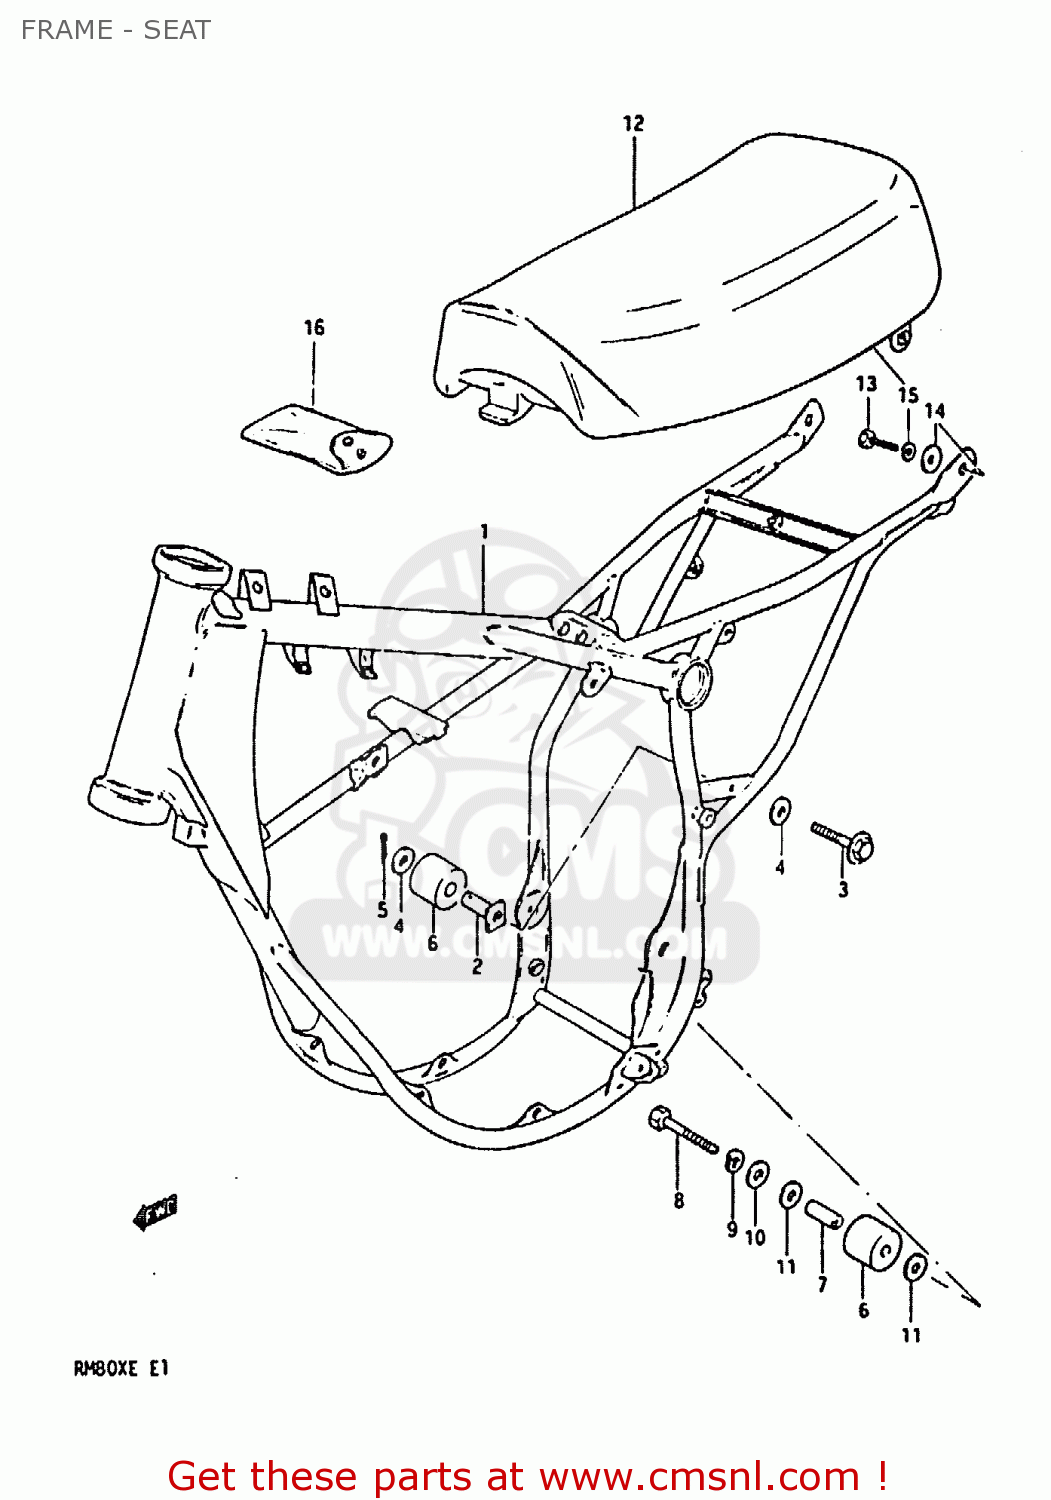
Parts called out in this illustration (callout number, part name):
1	FRAME
2	BOSS,CHAIN CONTROL
3	BOLT
4	WASHER
5	PIN 25X20
6	ROLLER,CHAIN LENGTH CONTROLLER
7	SPACER (6.5X10.5X29)
8	BOLT
9	WASHER,LOCK
10	WASHER, LOWER
11	LOCK WASHER
12	SEAT ASSEMBLY
13	BOLT
14	WASHER (6.5X18X1.6)
15	LOCK WASHER
16	TOOL SET
